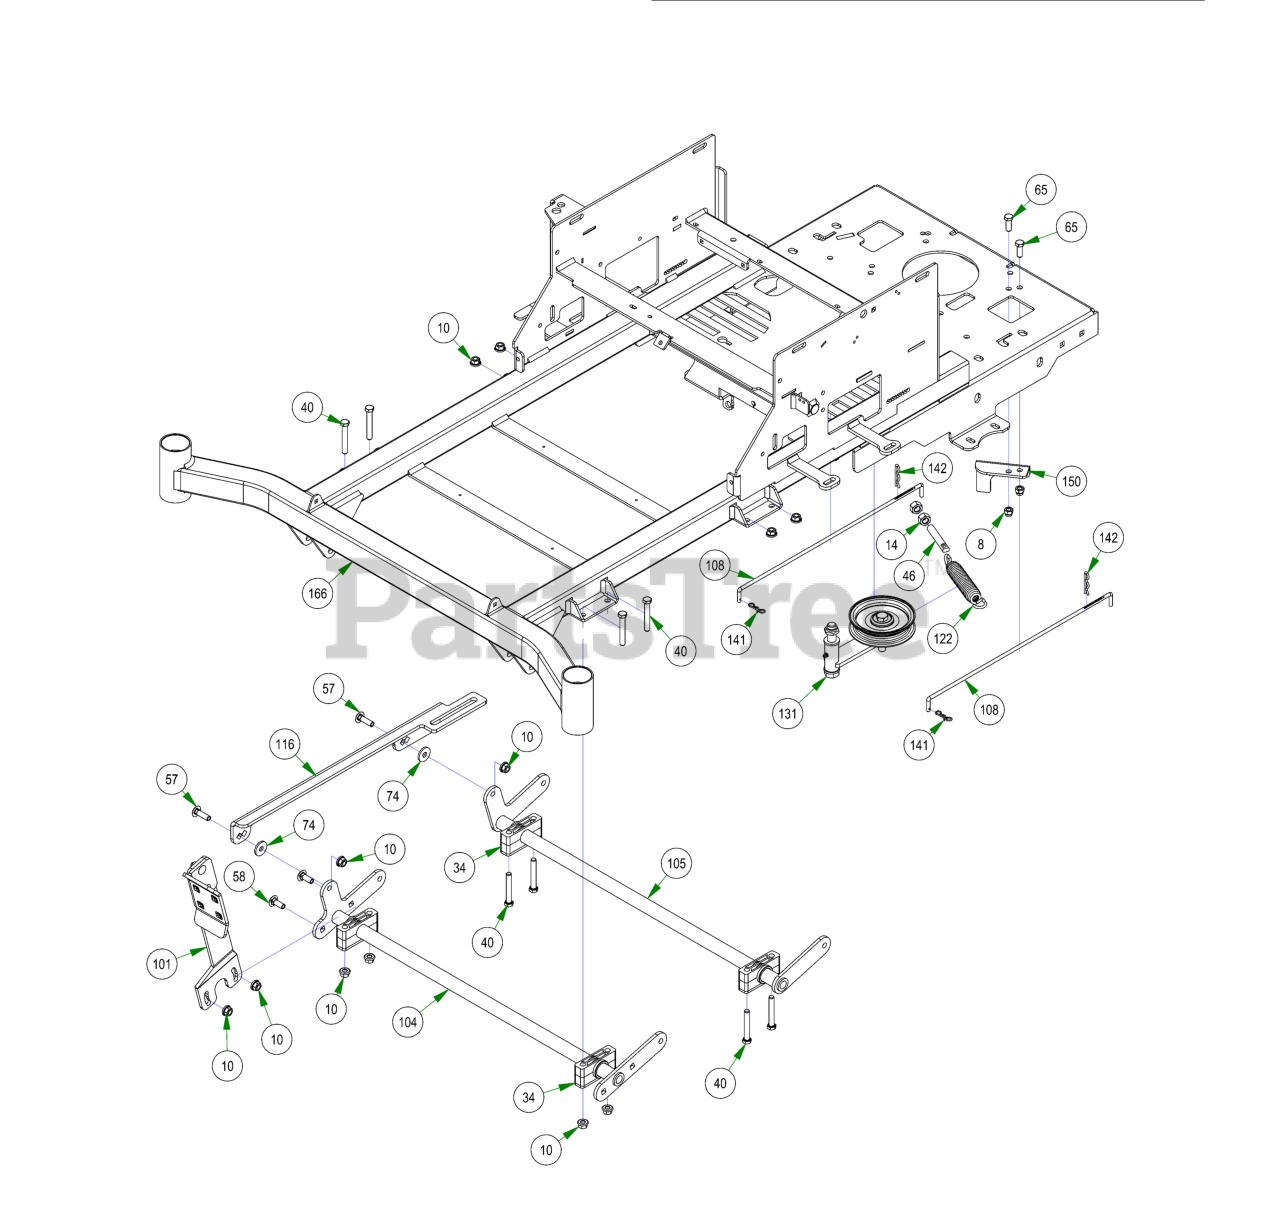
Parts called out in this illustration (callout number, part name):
8	3/8-16 NYLON INSERT LOCKNUT ZINC
10	3/8-16 NYLON INSERT FLANGE LOCKNUT (GR.F) ZINC
14	1/2-13 HEX NUT ZINC
34	Pillow Block Kit
40	3/8-16 X 2-1/2 HEX CAP SCREW (GR.5) ZINC
46	All Thread
57	3/8-16 X 1-1/4 CARRIAGE BOLT ZINC
58	3/8-16 X 1 CARRIAGE BOLT (GR.5) ZINC
65	3/8-16 X 1 GR 5 Hex Bolts Zinc
74	.390 ID X 1.12 OD X .125 THK FLAT WASHER NYLON
101	Foot Pedal Assembly
104	Actuator Bar Front- 2017 MZ/ZT
105	Actuator Bar Rear- 2017 MZ/ZT
108	Neutral Rod
116	2017 MZ/ZT Actuator Linkage
122	Deck Idler Spring
131	ZT Pump Idler
142	Neutral Rod Clip
150	2017 MZ Clutch Stop
166	2022 MZ/ZT 54"-60" Frame
